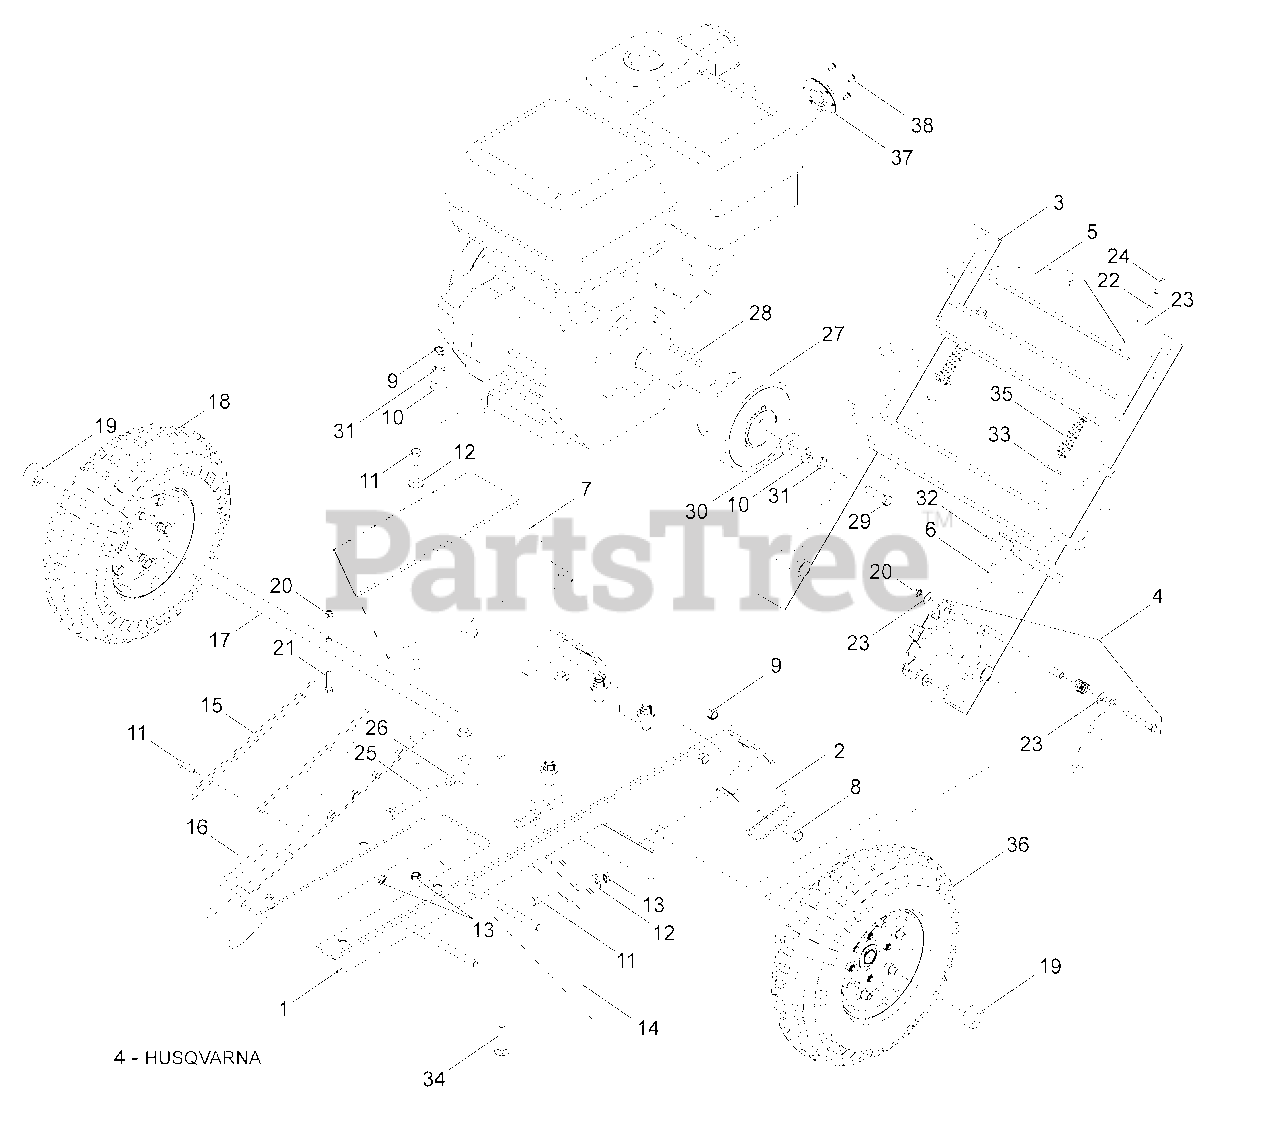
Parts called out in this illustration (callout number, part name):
3	HANDLE, LOWER
4	BRAKE, CALIPER
5	BRACKET, HANDLE
6	PIN, HANDLE ADJUSTMENT
8	HCS 3/8-16 x 1
9	NUT 3/8-16 CNTRLK
10	WASHER 3/8 FLAT STD
11	HCS 5/16-18 x ¾
12	WASHER 5/16
13	NUT 5/16-18 CNTRLK
14	DEFLECTOR, REAR
15	STRAP, DEFLECTOR
16	DEFLECTOR, SIDE
19	SET COLLAR, ¾"
20	NUT ¼-20 CNTRLK
21	HCS ¼-20 x 1¼
22	LOCKWASHER ¼
24	HCS ¼-20 x ¾
25	HCS 3/8-16 x 3½ TPBLT
26	NUT 3/8-16
27	CLUTCH -NORAM 3 SHOE
28	KEY ¼ SQ x 2½
29	HCS 3/8-24 x 1½
30	WASHER ½ FLAT
31	WASHER 3/8 SPLIT LK
32	PIN, COTTER 1/8 x ¾
33	WASHER ½, SAE
34	RHSNB 3/8-16 x 1¾
35	SPRING, COMPRESSION
36	WHEEL w/ DISC
37	DEFLECTOR, EXHAUST
38	SCREW #8-32 x 3/8
